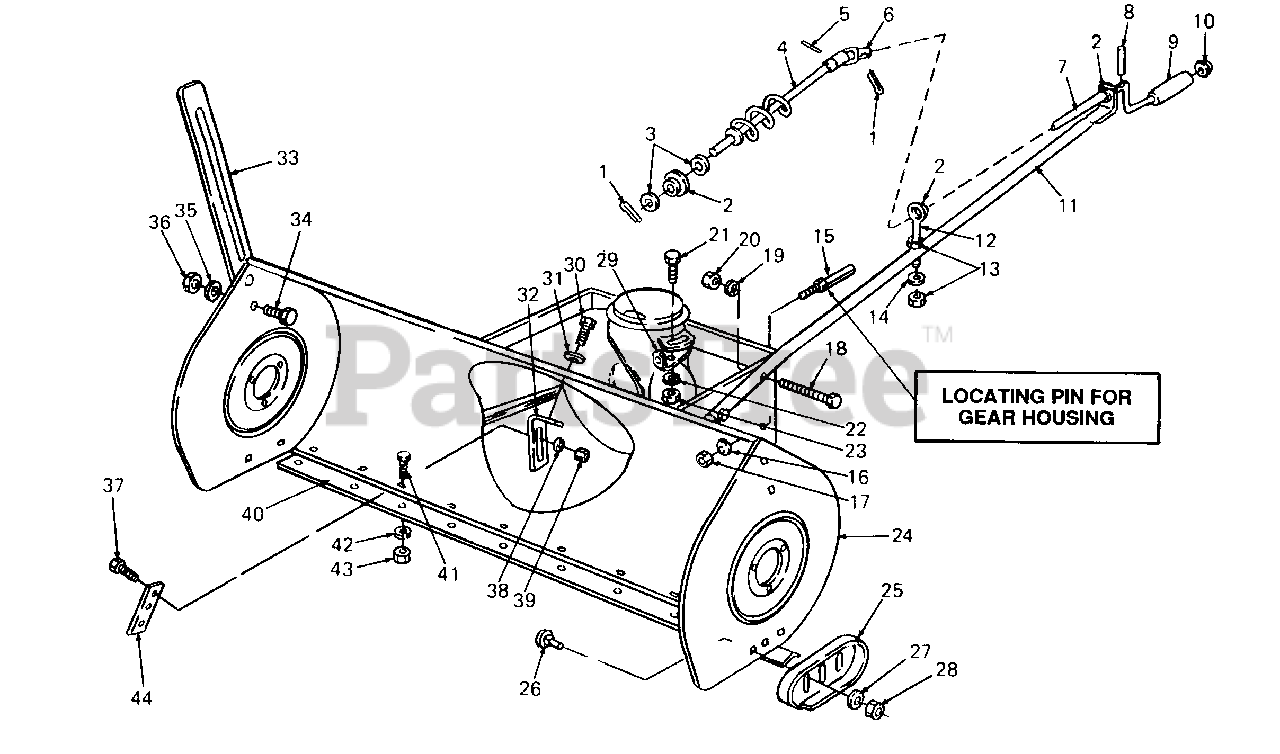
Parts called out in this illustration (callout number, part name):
1	Pin, Cotter, 3/32 Dia X .75 Lg
2	Bushing, Plastic
3	Washer, Flat, .385 X .62 X .063
4	Spiral, Chute Crank
5	Pin, Spiral Spring, 1/8 Dia X .812 Lg
6	Block Assy, Joint
7	Crank, Chute
8	Pin, Roll, 1/8 Dia X .63 Lg
9	Knob, Chute Crank
10	Pushnut, Rod, 3/8
13	Nut, Hex, 5/16-18
14	Washer, Bell, .345 X .88 X .060 Thk
15	Stud, Locating
16	Washer, Flat, .531 X .930 X .050 Thk
17	Nut, Hex Center Lock, 3/8-16
18	Screw, Hex Cap, 3/8-24 X 1.25 Lg GR5
19	Washer, Lock, 3/8
20	Nut, Hex Insert Lock, 3/8-24
21	Bolt, Carriage, 5/16-18 X .75 Lg
22	Washer, Bell, .345 X .88 X .060 Thk
23	Nut, Hex, 5/16-18
24	Housing Assy
25	Shoe, Slide
26	Bolt, Carriage, 3/8-16 X .62 Lg
27	Washer, Flat, .531 X .930 X .050 Thk
28	Nut, Hex, 3/8-16
30	Screw, Hex Wash AB Tapp
31	Washer, Bell, .345 X .88 X .060
34	Bolt, Carriage, 5/16-18 X .75 Lg
35	Washer, Lock, 5/16
36	Nut, Hex, 5/16-18
37	Screw, Hex Cap, 1/4-28 X .75 Lg GR5
38	Washer, Bell, .265 X .75 X .062 Thk
39	Nut, Hex, 1/4-28
41	Bolt, Carriage, 5/16-18 X 1.0 Lg
42	Washer, Lock, 5/16
43	Nut, Hex, 5/16-18
44	Plate, Gear Hsg Support
